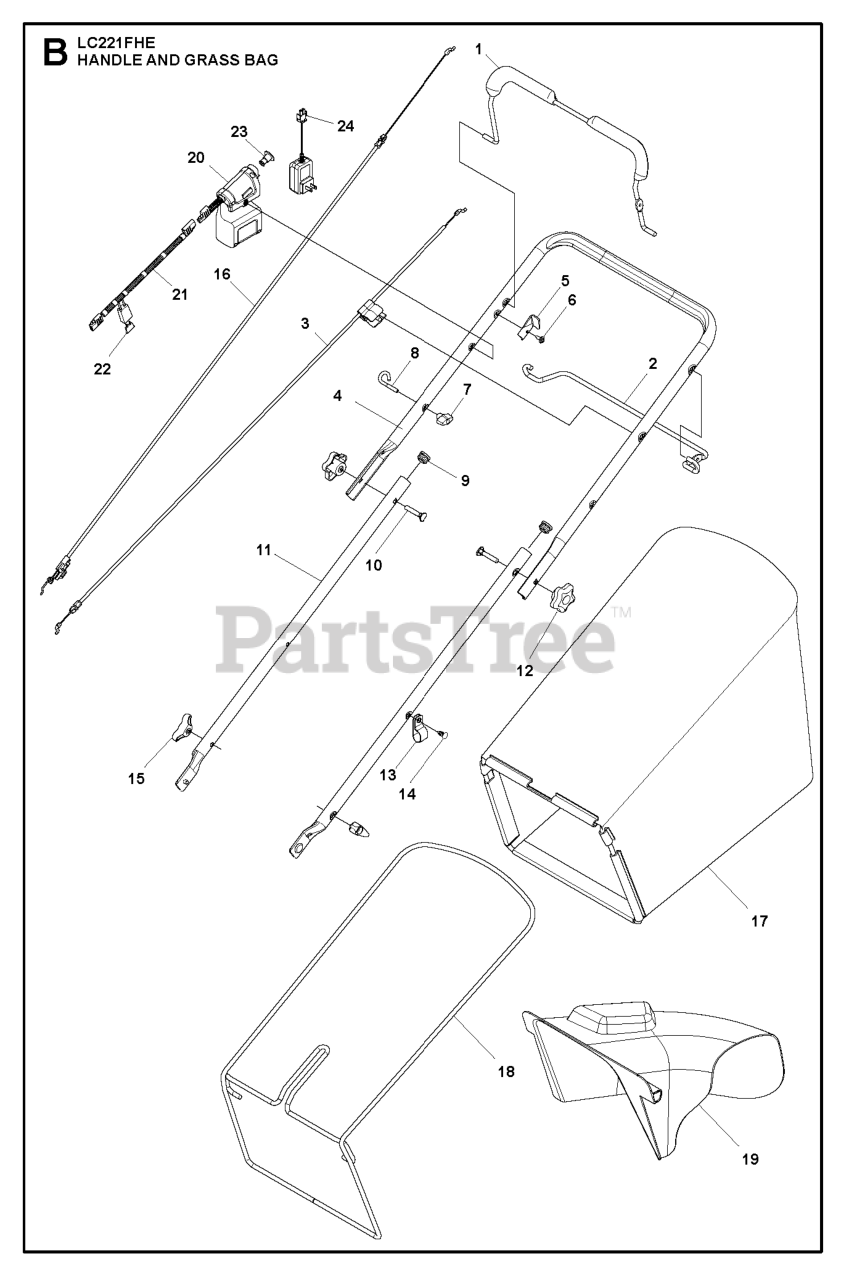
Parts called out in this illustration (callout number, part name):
1	BAIL.ARM.ASSY:STRAIGHT OM
2	BAIL.CONT.DR.S/S.ROUND.BLACK
3	RP.CABLE.MZR.RGD.PLUS.STRT
4	HANDLE.UP.DST.SS/VS.FG/RG.NHGY
5	BRACKET.UPSTOP.RT
6	SCREW
7	T-KNOB.NEW ROPE GUIDE
8	GUIDE.ROPE.BLK.ZINC.CHROM
9	PLUG.PLASTIC.7/8".14-20.GAUGE
10	BOLT.CONCAVE.HEAD.RETAINING
11	HANDLE.LOW.2PC.2POS.21EFF.498
12	KNOB.HANDLE.PLASTIC.STAR.BLACK
13	CLIP.CABLE.BLK
14	FASTENER.PUSH.O.250X0.783
15	KNOB, DEFLECTOR
16	CABLE DRIVE, FGD, 21 EFF ESTAR
17	GBAG.C361029ER.HUSQ.GRY.21EFF
18	FRAME.GBAG.AWD.21.BLACK
19	CHUTE.DISCHARGE.21EFF.HW
20	STARTER SYSTEM MODULAR E-START
21	WIRING ASSY E-START MODULE, MO
23	BUTTON.KEY.CYLINDER.BLACK
24	CHARGER.BATT.12V LEAD-ACID.DOM
